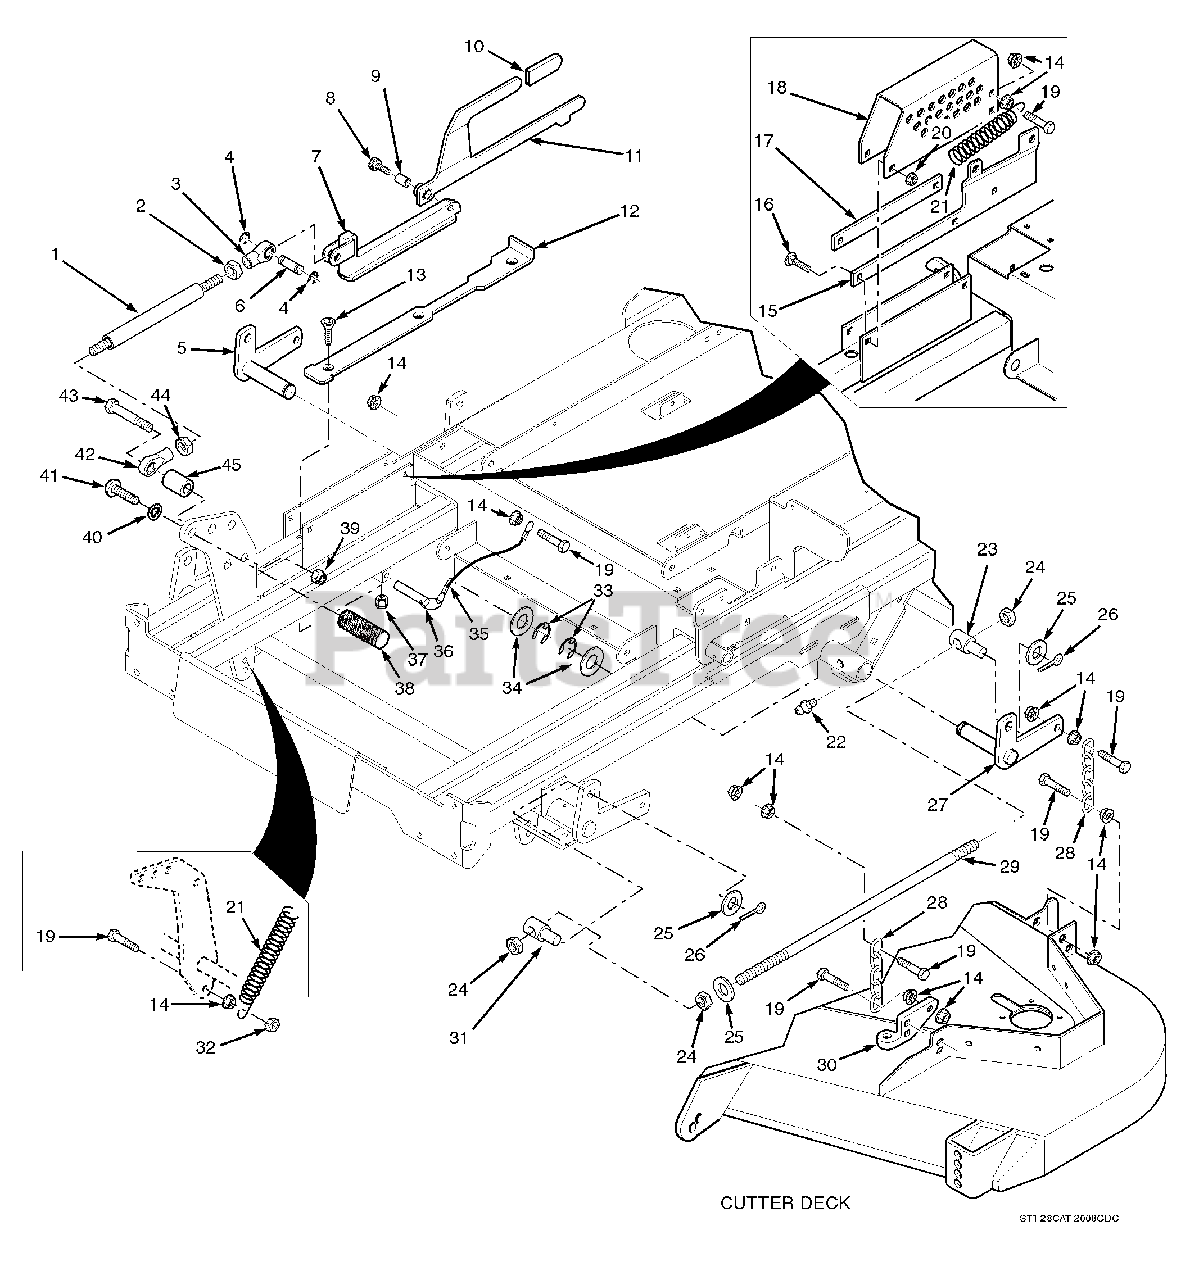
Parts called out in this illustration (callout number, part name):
1	Link, Deck Lift
2	Nut, Jam 1/2-20 LH
3	Rod End, Female - 1/2-20 LH
4	Ring, Retaining 1/2” External “E”
5	Bellcrank Weldment, RH Rear
6	Pin, Decklift
7	Slide Weldment, Height Adjustment
8	Bolt, Shoulder 1/2 x 3/4”
9	Bushing, .502 ID.
10	Grip, Deck Latch
11	Deck Latch
12	Lockplate, Decklift
13	Screw, Cap 5/16-18 x 3” FHHS
14	Nut, Hex Serrated Flange 3/8-16
15	Guide, Long
16	Bolt, Carriage 5/16-18 x 1”
17	Guide, Short
18	Bracket, Cutting Height Adjustment
19	Bolt, Hex Head 3/8-16 x 1-1/2”
20	Nut, Hex Serrated Flange 5/16-18
21	Spring, Helper
22	Grease Fitting
23	Swivel Joint, LH
24	Nut, Hex 5/8-11
25	Flatwasher, 5/8”
26	Cotter Pin, 3/16 x 1”
27	Bellcrank Weldment, LH Rear
28	Chain
29	Stud, 5/8-11 x 26.0”
30	Lever Assembly, Deck Level
31	Swivel Joint, RH
32	Locknut, 3/8-16 Center Lock
33	Ring, Retaining 1” External “E”
34	Flatwasher, 1”
35	Lanyard, Deck Height Pin
36	Ring Pin, 1/2 x 3.06”
37	Nut, 3/8-16 Elastic Stop
38	Foot Pedal, Height Adjustment
39	Nut, Hex Elastic Stop 1/2-13
40	Lockwasher, 5/8”
41	Capscrew, 5/8-11 x 1-1/2”
42	Rod End, Female - 1/2-20 RH
43	Bolt, Hex Head 1/2-13 x 3”
44	Nut, Jam 1/2-20 RH
45	Spacer, Decklift Pedal
